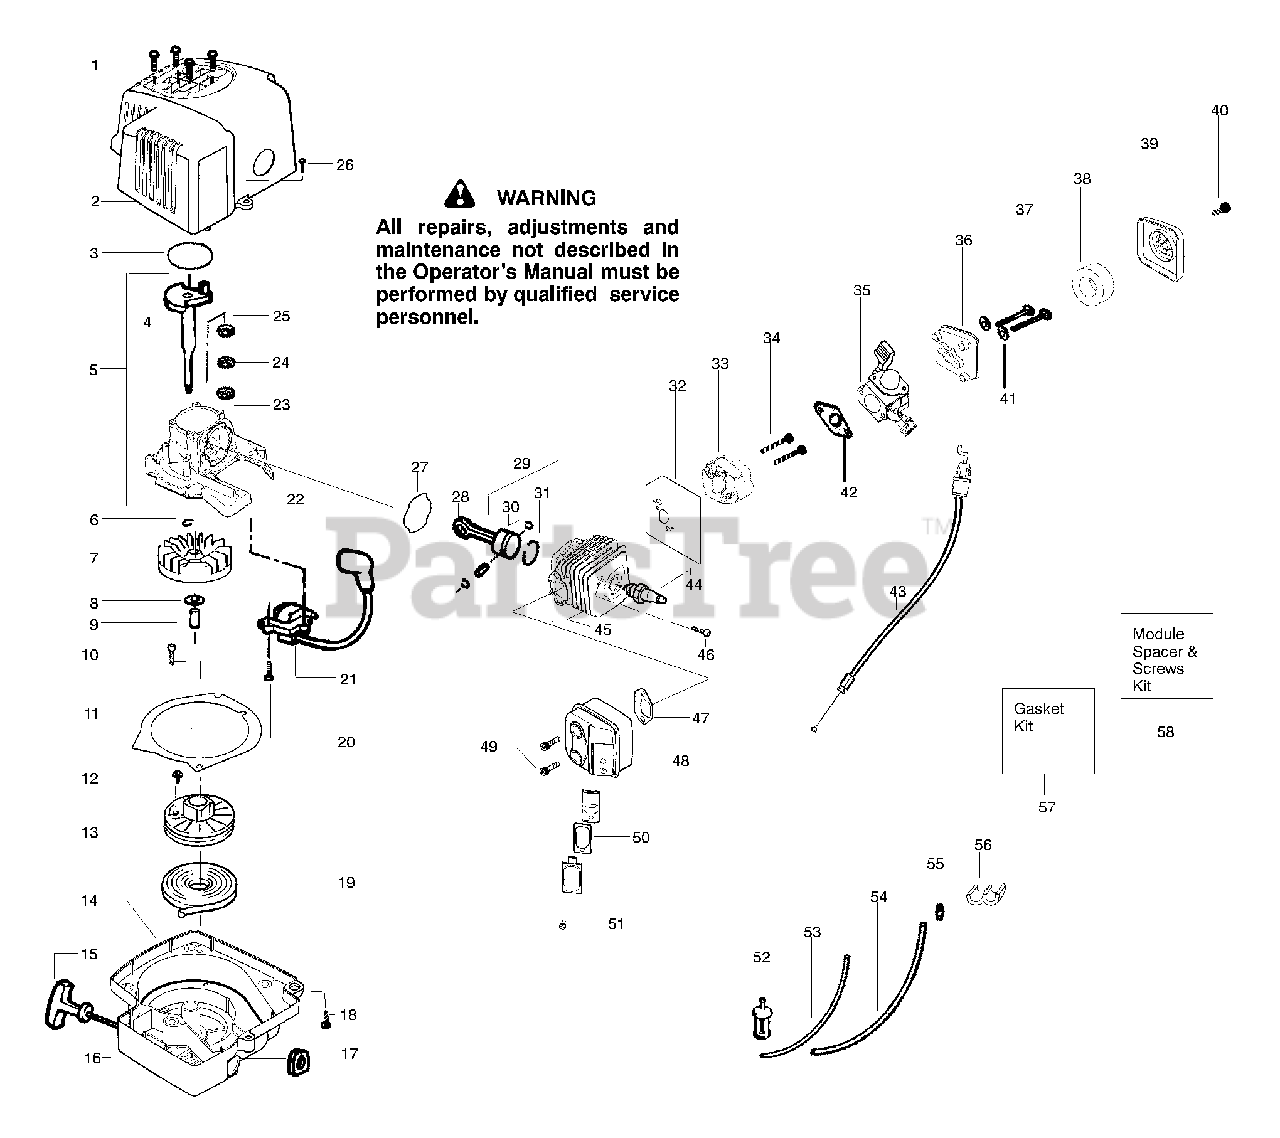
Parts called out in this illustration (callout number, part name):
2	Assy-Shroud/H'shield
3	O-Ring-C'case (kit)
4	Assy-Crankshaft
5	Assy-C/case-C/shaft
6	Ring-Retainer-C'shaft
7	Assy-Flywheel
8	Washer-Flat
9	Spacer-Flywheel
11	Plate-Baffle
13	Kit-Starter Pulley
14	Assy-Fan Housing
15	Handle-Starter
16	Kit-Rope
17	Grommet-Ignition Module
18	Screw-(f/hsg to shrd)
19	Spring-Starter
21	Ignition Module
22	Assy-Crankcase
23	Bearing-Outer
24	Seal-Crankcase
25	Bearing-Inner
27	Seal-Cylinder (kit)
28	Assy-Connecting Rod
29	Kit-Piston
30	Retainer-Piston Pin
31	Ring-Piston
32	Gasket-Carb. Adapt.(kit)
33	Adapter-Carburetor
35	Kit-Carburetor Ass'y. (C1U-W13A)
38	Air Filter Foam
39	Air Filter Cover
41	Washer
42	Gasket-Carburetor(kit)
43	Assy-Throttle Cable
44	Spark Plug(RCJ-6Y)
45	Kit-Cylinder
47	Gasket-Muffler (kit)
48	Kit-Muffler
49	Bolt-Muffler
50	Kit-Spark Arrestor
52	Assy-Pick-up
53	Kit-Fuel Line(small)
54	Kit-Fuel Line(large)
55	Fitting-Fuel Line
56	Clip-Retainer
57	Kit-Gasket
58	Kit-Module Spacer & Screws
